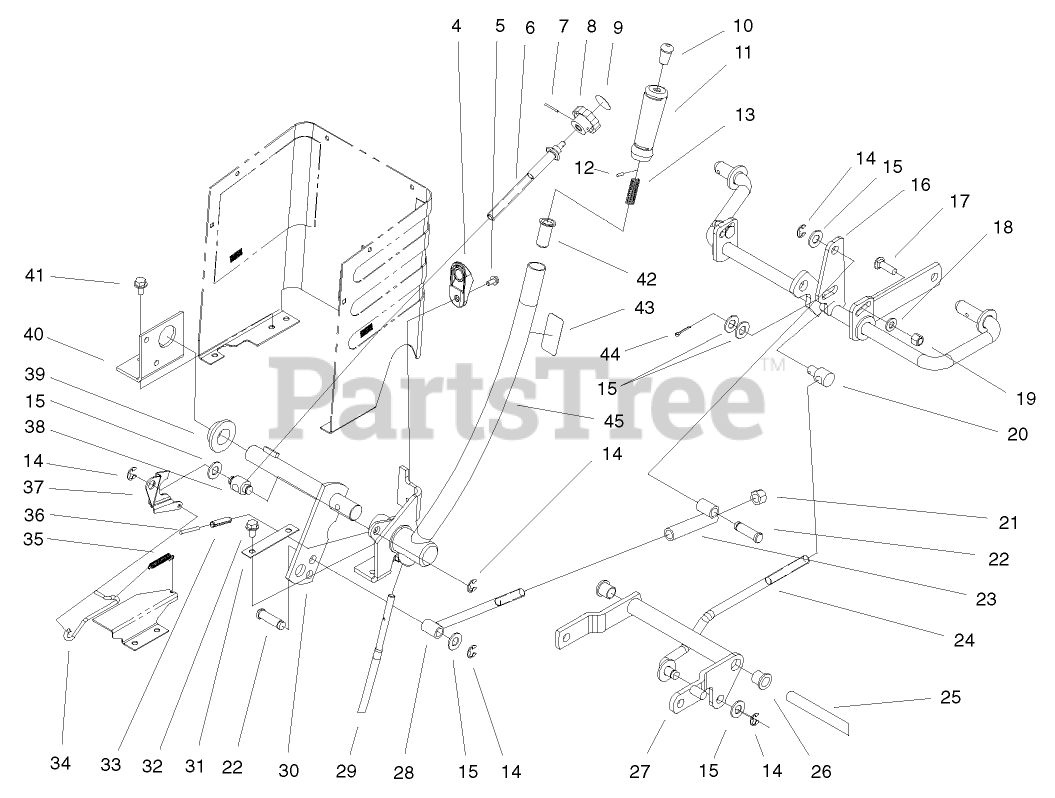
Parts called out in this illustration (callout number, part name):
4	WEDGE - HOC
5	SCREW-HWH
7	PIN-SPIROL
10	TIP-ROD
11	GRIP-HANDLE
12	PIN-SPIROL
13	SPRING-COMPRESSION
14	RING-RETAINING, EXTERNAL
15	WASHER-FLAT
16	SHAFT-GAGE
17	BOLT-CARR
18	WASHER-FLAT
19	NUT-LOCK, NI
21	NUT-LOCK, NI
26	BUSHING-FLANGE
27	ARM-PIVOT
29	ROD-LEVER, LIFT
30	SHAFT-LIFT
32	SCREW-HWHTF
33	PIN-ROLL
34	ROD - HOC INDICATOR
35	SPRING - EXTENSION
36	PIN-SPRING
37	PLATE - HOC GAGE
39	BEARING-FLANGE
40	BRACKET-PIVOT, LINKAGE
41	SCREW-HWHTF
42	RETAINER-SPRING
43	DECAL-LIFT
44	PIN-COTTER
45	LEVER-LIFT
